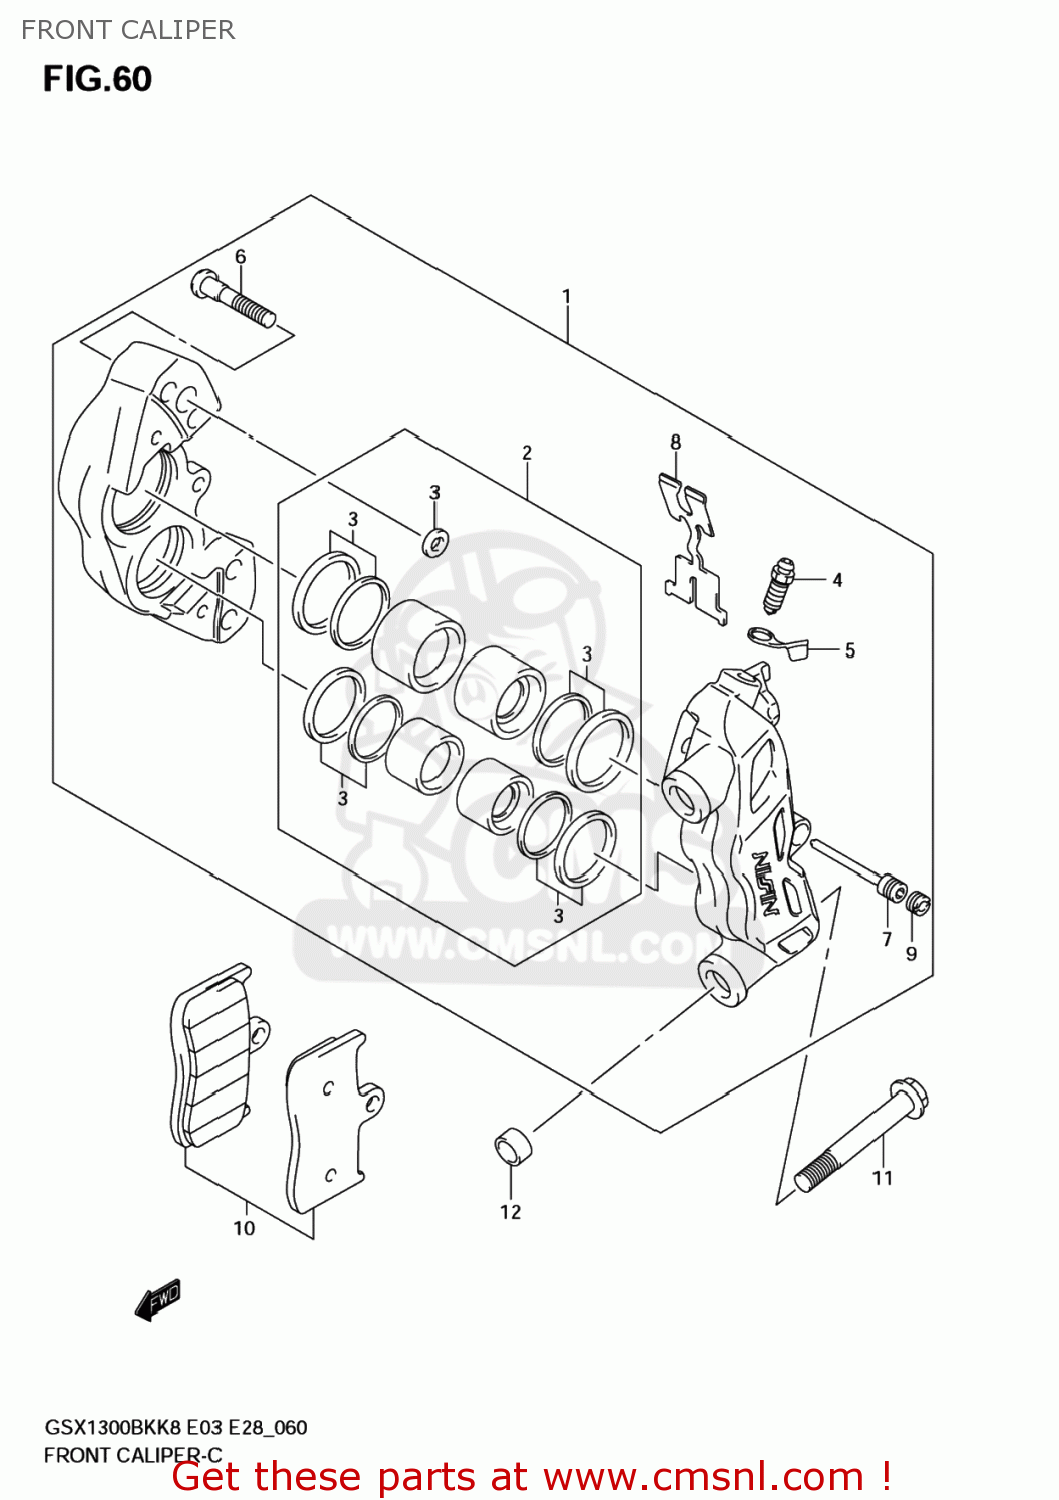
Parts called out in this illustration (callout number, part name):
1	CALIPER ASSY,FR,R
2	PISTON SET
3	SEAL SET,PISTON
4	BLEEDER
5	CAP,BLEEDER
6	BOLT
7	PLUG,PIN
8	SPRING,PAD
9	PIN,HOLDER
10	PAD SET (NAS)
11	BOLT(10X70)
12	PIN,CALIPER
